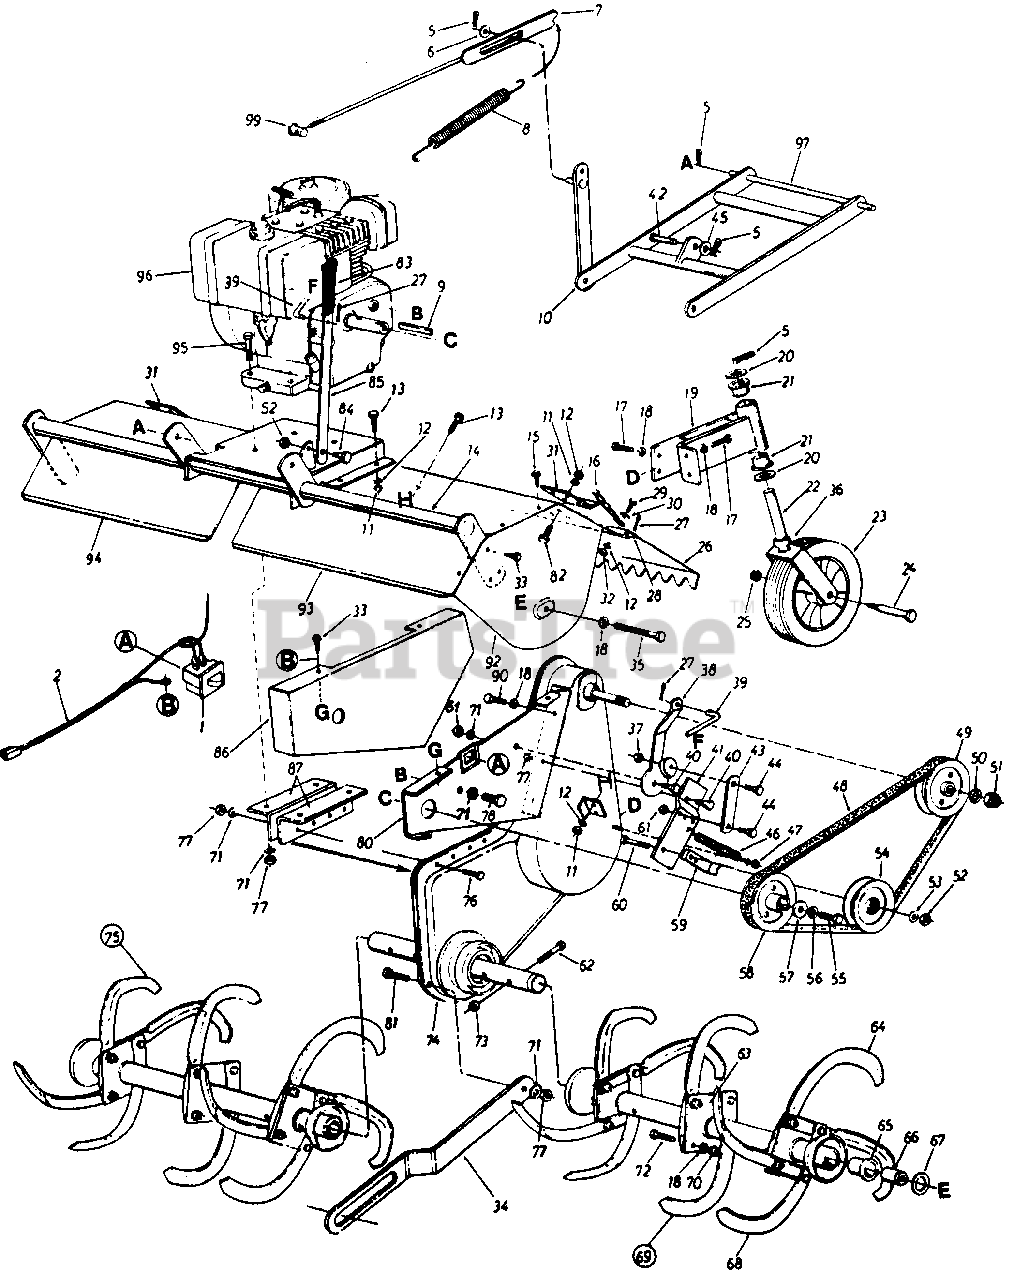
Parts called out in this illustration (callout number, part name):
1	Safety Switch
2	Wire Harness
5	Internal Cotter Pin
6	Fl-Wash. 1/2" I.D. x .93" O.D.
9	Sq. Key 1/4" X 1/4" X 2.00" Lg.
12	L-Wash. 1/4" I.D.'
13	Hex Bolt 28 X .62" Lg.
16	#2 Dog Chain x 20" Lg.
17	Hex Wash. Hd. Self-Tap Scr. 3/8-24 X .75" Lg.
18	L-Wash. 3/8" I.D.
19	Swivel Wheel Support
20	Fl-Wash. 3/4" I.D. x 1.50" O.D.
21	Flange Bearing 3/4" I.D. x 1.00" O.D.
22	Swivel Wheel Caster
23	Wheel Assembly 10.0 x 2.75
24	Shoulder Bolt .623" I.D. x 3.62" Lg.
25	Hex Cent. L-Nut 7/16-14 Thd.
28	L.H. Flap Rod
28	R.H. Flap Rod
29	Hex Bolt 1/4-20 X .62 Lg.
30	Fl-Wash. 1 l" I.D.
33	Hex Wash. Hd. Self-Tap Scr. 1/4 " X .62" Lg.
34	Stabilizer Link
35	Hex Bolt 3/8-16 X 1.25" Lg.
36	Spacer .752" l.D. x 1.25" O.D.
37	Hex Cent. L-Nut 5/1618 Thd.
40	Shoulder Bolt 7/16" Dia. x 1.75n Lg.
45	Fl-Wash. .50n l.D. x 1.0" O.D. x .0
46	Extension Spring .62tt O.D. x 6.12n Lg.
47	Hex Crown Nut 3/8-24 Thd.
48	V-Belt (Kevlar)
49	1/2" "V"-Pulley 4.75" O.D. x .625" Bore
50	L-Wash. 5/8' I.D.
51	Hex Ins. L-Nut 5/8-18 Thd.
52	Hex Cent. L-Nut 3/8-16 Thd.
53	Fl-Wash. 3/8 I.D.
54	Idler Pulley 4.0" O.D.
55	Hex Bolt
56	L-Wash. 7/16n l.D.
57	Fl-Wash. 7/16n l.D. x 1.38n
58	1/2" "V"-Pulley ,475n O.D. x 1.00' Bore
61	Hex Cent. L-Nut 5/16-18 Thd.
62	Hex Bolt 7/16-14 X 2.00 Lg.
65	Flange Bearing 1.00" I.D.
66	Spacer
67	Thrust Wash. 1/2n l.D. x 1.55n
68	Tine-R.H.
69	Tine Assembly Comp.-L.H.
70	Hex Nut 3/8-24 Thd.
71	L-Wash. 5/16" I.D.
72	Hex Bolt 3/8-24 X 1.5" Lg.
73	Hex Cent. L-Nut 7/16-14 Thd.
77	Hex Nut 5/16-18 Thd.
78	Hex Bolt 5/16-24 x .62"
80	Clutch Support Bracket
81	Shld. Bolt .435 Dia. x .265 5/1 6-1 8 Thd.
82	Hex Bolt 28 x ,75n Lg.
83	Plastic Grip
84	Shoulder Bolt .498 Dia. X .212 Lg.
87	Engine Mounting Bracket
90	Hex Bolt 3/8-16 X .62" Lg.
92	L.H.-Side Plate
96	8 H.P. Engine
97	Hitch Rod
99	Ferrule
